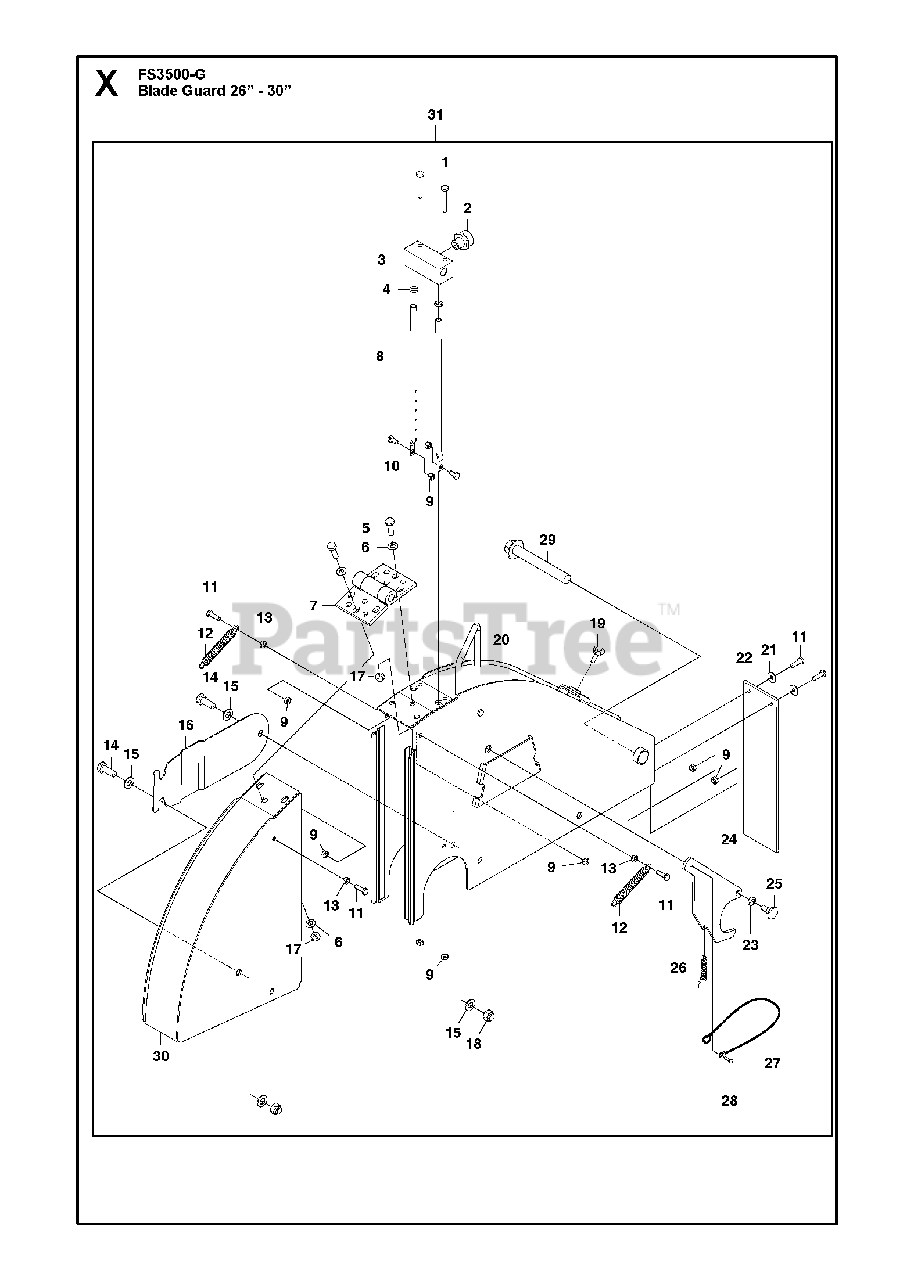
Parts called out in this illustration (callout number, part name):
6	WASHER
9	HEXAGON LOCKING NUT
15	WASHER
17	HEXAGON LOCKING NUT
18	HEXAGON LOCKING NUT
